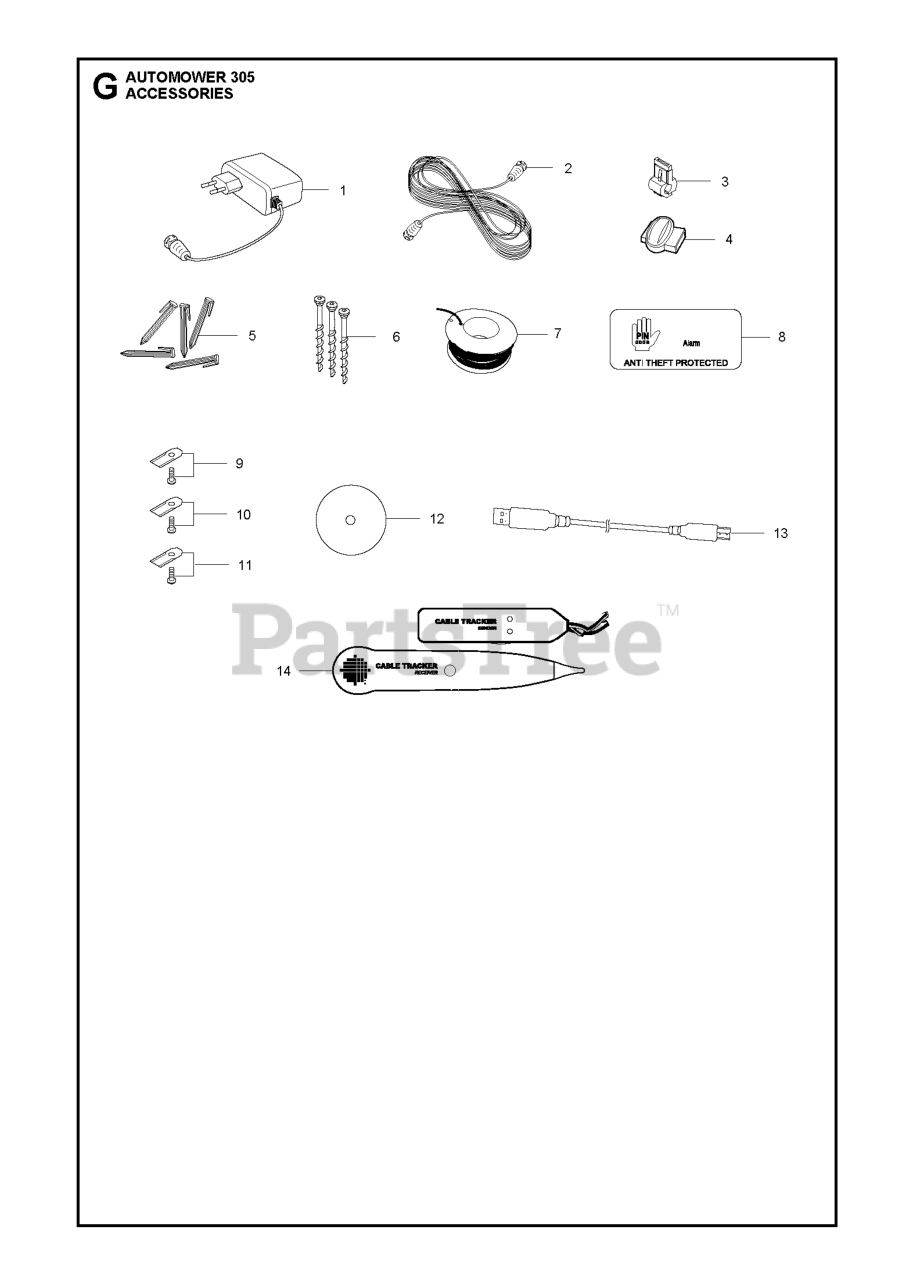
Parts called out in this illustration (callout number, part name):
3	BRAKER
4	SPLICE KIT
5	STAPLES (100 CT BAG)
6	SCREW KIT KIT INCLUDES THREE S
7	LOOP WIRE 250M
9	BLADE
10	BLADE - 30 PCS
11	BLADE - BULK PACK 500 PCS
14	TEST EQUIPMENT
